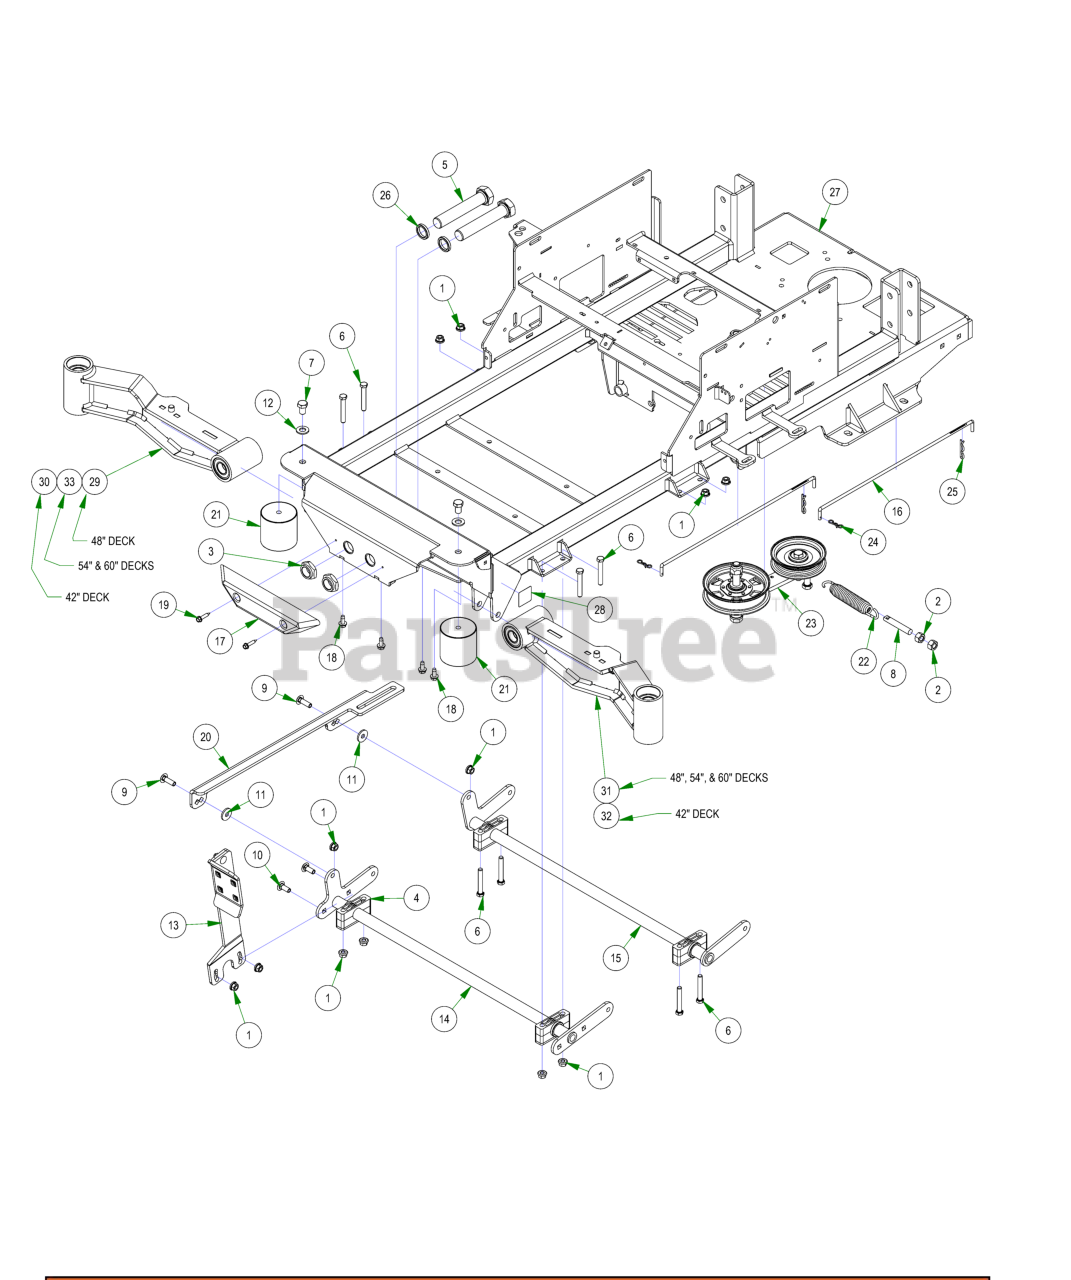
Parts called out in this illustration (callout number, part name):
1	3/8-16 NYLON INSERT FLANGE LOCKNUT (GR.F) ZINC
2	1/2-13 HEX NUT ZINC
3	1"-14 NYLON INSERT JAM LOCKNUT ZINC
4	Pillow Block Kit
5	1"-14 X 5-1/2 HEX CAP SCREW (GR.8) ZINC YELLOW
6	3/8-16 X 2-1/2 HEX CAP SCREW (GR.5) ZINC
7	1/2-13 X 3/4 HEX CAP SCREW (GR.5) ZINC
8	All Thread
9	3/8-16 X 1-1/4 CARRIAGE BOLT ZINC
10	3/8-16 X 1 CARRIAGE BOLT (GR.5) ZINC
11	.390 ID X 1.12 OD X .125 THK FLAT WASHER NYLON
12	1/2 SAE FLAT WASHER (1-1/16" OD) GR.8 ZINC YELLOW
13	Foot Pedal Assembly
14	Actuator Bar Front- 2017 MZ/ZT
15	Actuator Bar Rear- 2017 MZ/ZT
16	Neutral Rod
17	Bumper EZT
18	5/16-18 X 3/4 HEX WASHER SLOT (F) TCS ZINC
19	1/4-14 X 1-1/4 HEX WASHER UNSLOT TEK/3 ZINC
20	2017 MZ/ZT Actuator Linkage
21	Vibration Mount- Red Dot
22	Deck Idler Spring
23	Maverick Pump Idler
25	Neutral Rod Clip
26	Spacer, 1x1.375x.25
27	2023 Maverick Frame - Painted
28	Independetly Articulating Front Suspension Arms Patent Decal
29	2021 Maverick RH Short Front Suspension Arm Assy (48")
30	42" Maverick HD Front Suspension Arm Assy RH
31	2021 Maverick LH Front Suspension Arm Assy (48", 54" & 60")
32	42" Maverick HD Front Suspension Arm Assy LH
33	2021 Maverick RH Long Front Suspension Arm Assy (54" & 60")
